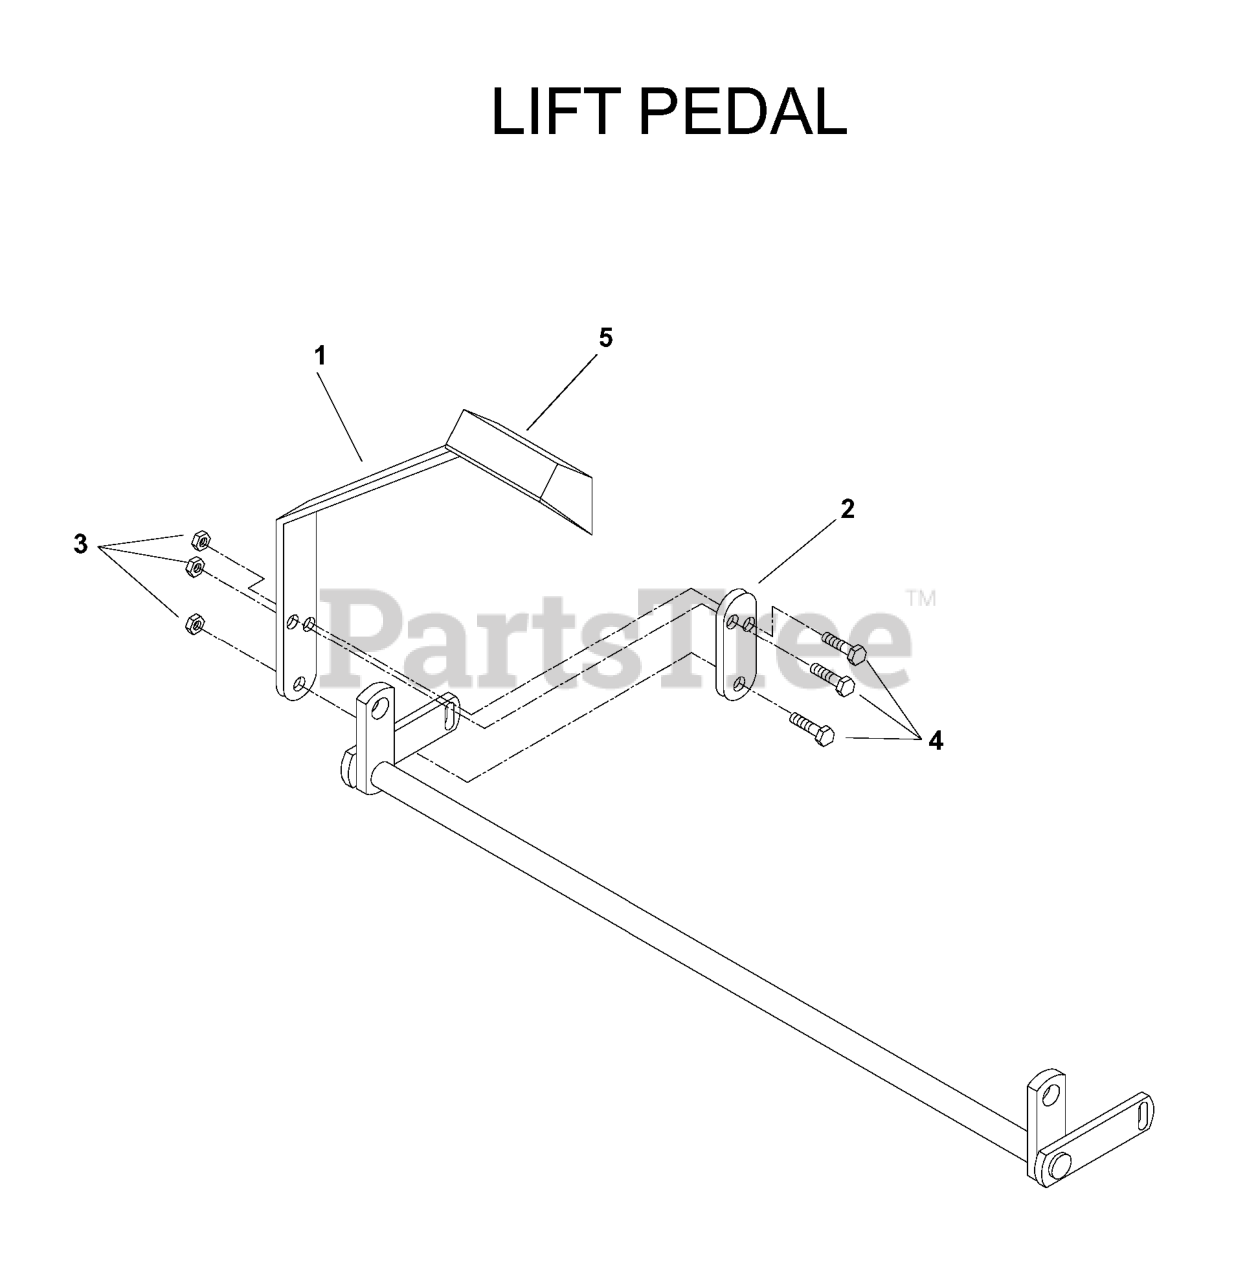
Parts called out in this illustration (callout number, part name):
1	LIFT PEDAL W/PAD
2	TIGHTENING PLATE
3	NUT 3/8-16 NYLOC
4	HCS 3/8C X 1 1/2
5	ANTI-SKID PAD
